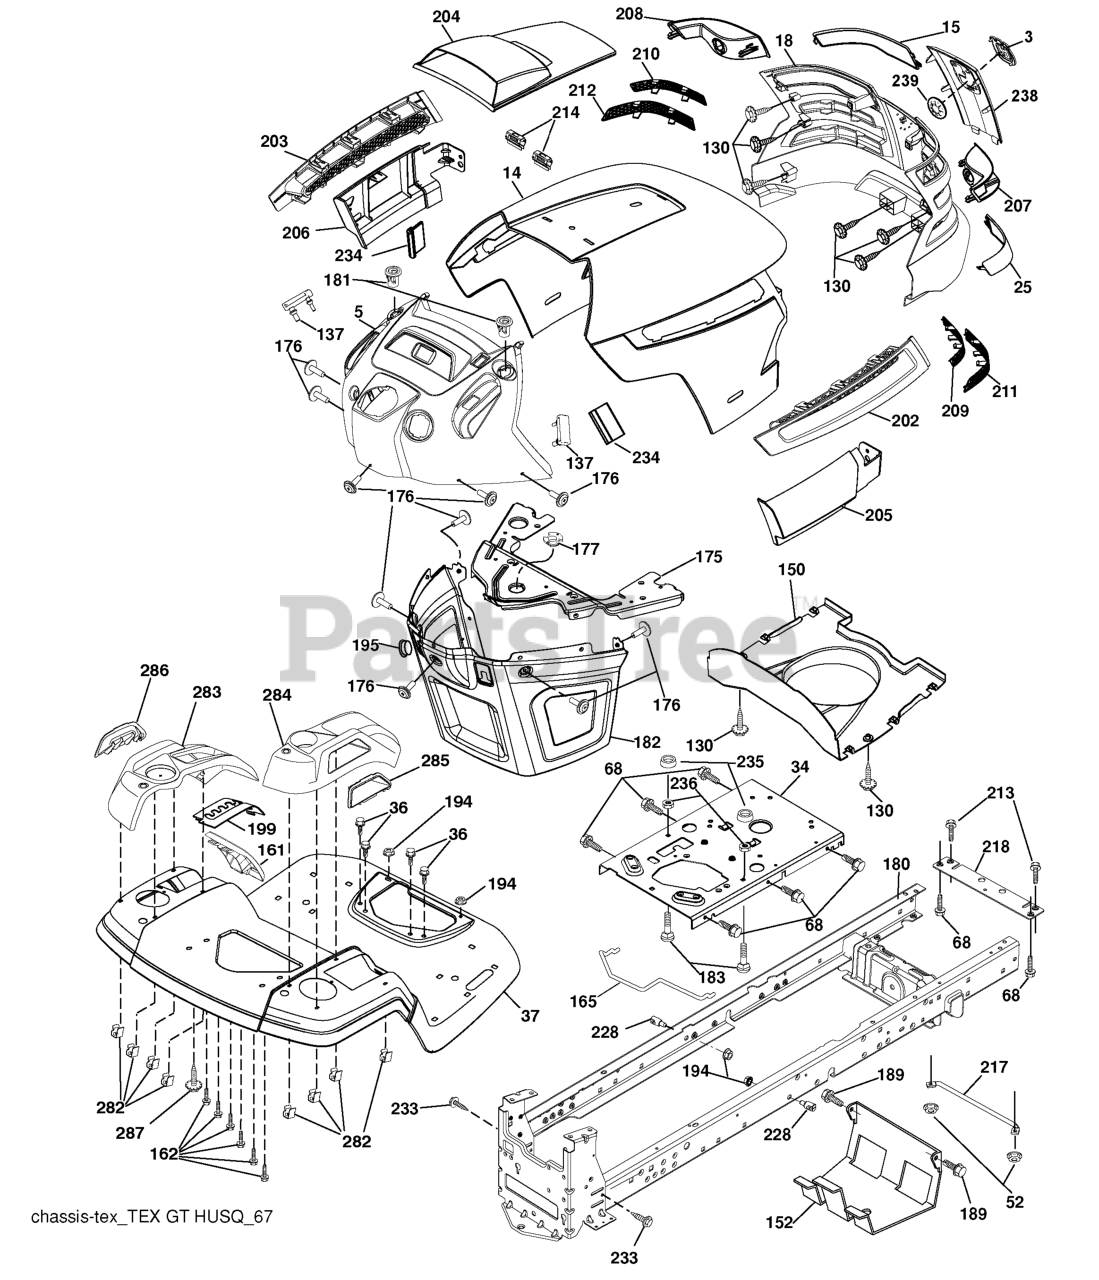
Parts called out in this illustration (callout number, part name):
3	RP LOGO
5	DASH.ASM.HUSQ.GT
14	HOOD
15	LENS.LH.TEX.GT.HUSQ.CL
18	GRILL.ASM.HUSQ.TG/CRD.W/TRIM
25	LENS.RH.TEX.GT.HUSQ.CL
34	PLATE.ENGINE.WELDED.CHASSIS
36	SCREW 5/16"
37	FENDER.TLT.FS.W/CPH/FW/RSF.ORN
52	LOCKNUT
68	Screw 5/16-18 x 1/2
130	SCREW.#10 X 0.750.BOS
137	BUMPER DASH
150	AIR.DUCT.HOOD.TEX.GT.HUSQ
152	SHIELD.BROWNING.W/TEX
161	WINDOW FUEL
162	SCREW.HI-LO.CONSOLE
165	SUPPORT.TANK.REAR.W/TEX
175	PLATE.CROSSMEMBER.HUSQ
176	SCREW.#10-24X5/8.RN.QU
177	BUSHING, STEERING
180	CHASSIS
181	BUSHING.MNT.FEND.CRGO.
182	DASH.LOWER.COMMON.12V.ADAPTOR
183	BOLT.5/16-18X1-1/4 FULL THD
189	SCREW
194	NUT LOCK HEX FLANGE 5/16-18
195	PLUG.HOLE.DASH.LOWER.12V.BLK
199	PLATE.DECK.LIFT.HUSQ.LT
202	VENT.SIDE.HOOD.HUSQ.RH.GREY
203	VENT.SIDE.HOOD.HUSQ.LH.GRAY
204	HOOD VENT
205	SKIRT.HOOD.SIDE.HUSQ.RH.GREY
206	SKIRT.HOOD.SIDE.HUSQ.LH.GREY
207	BEZEL.RH.TEX.GT.HUSQ
208	BEZEL.LH.TEX.GT.HUSQ
209	INSERT.HEX.GRILL.HUSQ.GREY
210	INSERT.HEX.GRILL.HUSQ.
211	INSERT.HEX.GRILL.HUSQ.
212	INSERT.HEX.GRILL.HUSQ.
213	BOLT
214	CLIP.RETAINER.TINNER.
217	ROD.PIVOT.HOOD
218	X-PIECE.HOOD.STOP.NON/
228	STUD.FASTNER.W/ANTI-ROTATE
233	BOLT.SHOULDER
234	BUMPER.HOOD.TEX.HUSQVARNA
235	SPACER FENDER
236	NUT.CENTERLOCK.5/16-
238	TRIM.HUSQ.TG/CRD.SERVICE
239	NUT PUSH M
282	CLIP.RETAINER.CONSOLE.LT.HUSQ
283	CONSOLE.DECK.LFT.R.SDFL.HUSQLT
284	CONSOLE.CNTRL.
285	CONSOLE INSERT RH
286	CONSOLE.INSRT.LH.HUSQ.LT.BLACK
287	SCREW 1/4X20
